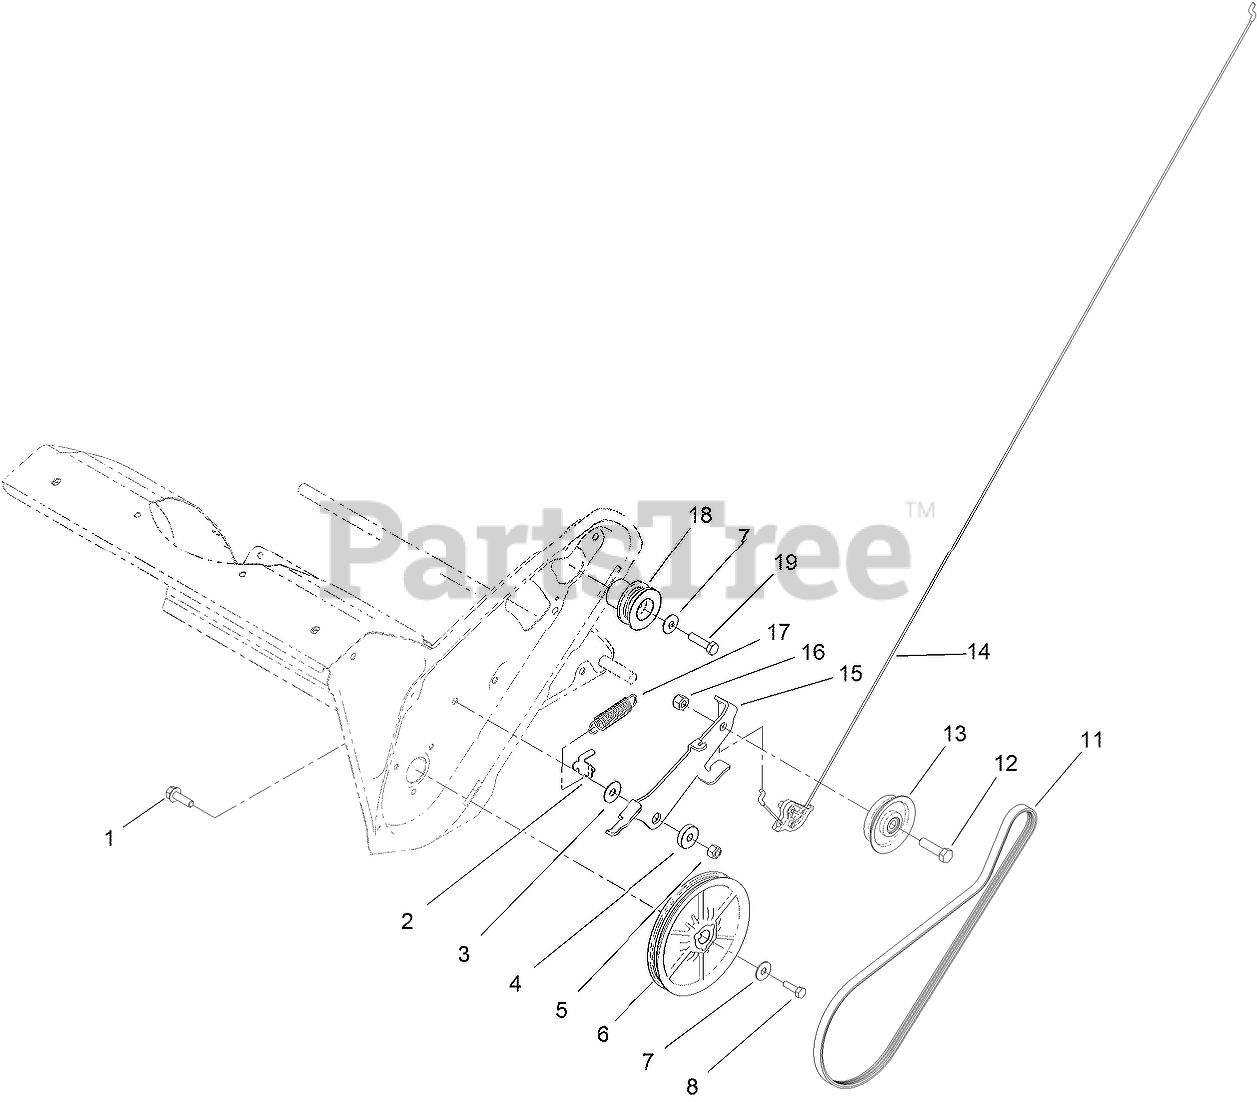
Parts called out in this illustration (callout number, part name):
1	SCREW-HHF
2	CLIP-SPRING, BRAKE
3	WASHER
4	BUSHING-PIVOT
5	NUT-LOCK, NI
6	PULLEY
7	WASHER-BELLEVILLE
8	SCREW-HH
11	BELT-DRIVE
12	SCREW-HH
13	PULLEY-IDLER
14	CABLE-CLUTCH
15	ARM-IDLER
16	NUT-LOCK, CONE
17	SPRING-EXTENSION
18	PULLEY-ENGINE
19	SCREW-HH
